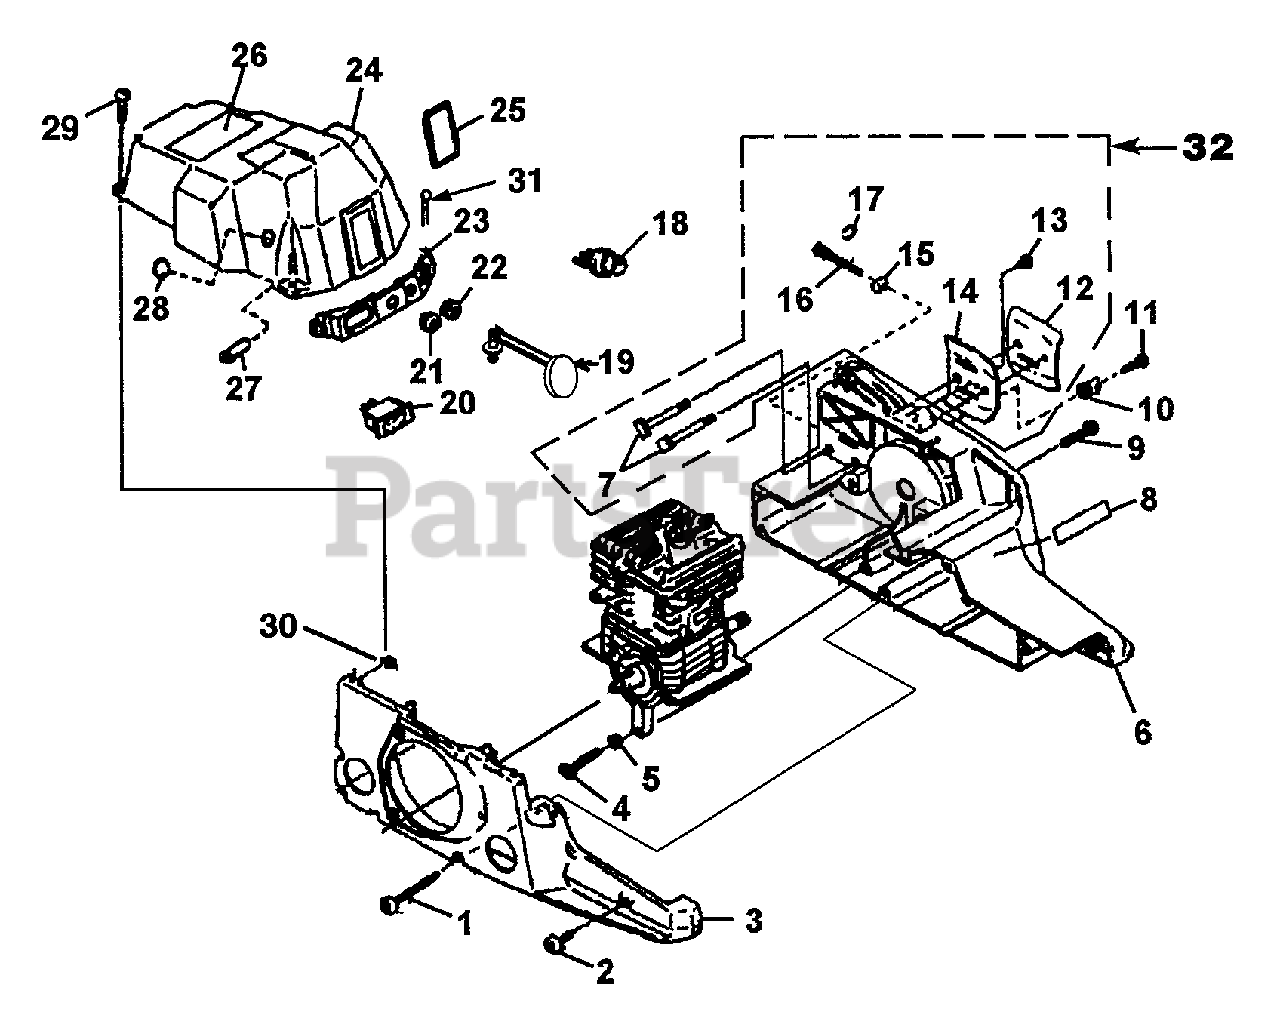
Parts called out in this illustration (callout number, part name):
1	SCREW- Thread Form. (8-16 x 1 3/4")
2	SCREW- Thread Form. (8-16 x 5/8")
3	HOUSING-Starter Side
4	SCREW-Thread Form. (10-14 x 1 1/8")
5	WASHER-Lock
6	HOUSING- Drive Side
7	BOLT- Guide Bar
8	DECAL- Panel
9	SCREW-Hex Hd. (12-24 x 1")
10	STOP- Chain
11	SCREW- Thread Form (10-14 x 7/8")
12	PLATE- Guide Bar (Outer)
13	SCREW- Thread Form. (6-19 x 1/2")
14	PLATE- Guide Bar (Inner)
15	PIN- Adjusting
16	SCREW- Guide Bar Adjusting
17	RING- Snap
18	BULB- Primer
19	ROD- Choke
20	SWITCH- Ign.
21	BOOT- Throttle Cable
22	GROMMET- Choke
23	PANEL- Control
24	CYLINDER COVER
25	SCREEN- Air Inlet
26	LABEL- Warning
27	GROMMET- Carburetor
28	PLUG- Idle Speed
29	SCREW- Round Hd. (10-24 x .710)
30	NUT- Square (10-24)
31	PIN-Cotter
32	GUIDE BAR FASTENER KIT
